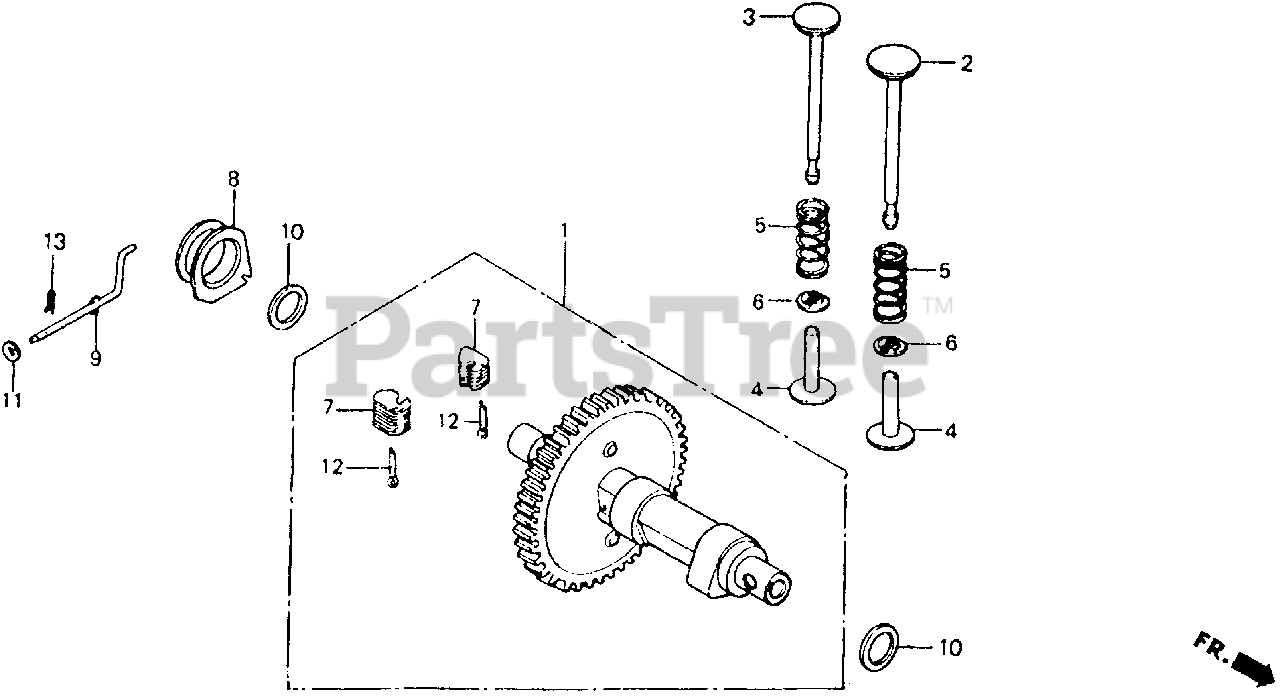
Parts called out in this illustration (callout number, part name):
1	CAMSHAFT ASSY.
2	VALVE, IN.
3	VALVE, EX.
4	LIFTER, VALVE (34.39)
4	LIFTER, VALVE (34.66)
5	SPRING, VALVE
6	RETAINER, VALVE SPRING
7	WEIGHT, GOVERNOR
8	SLIDER, GOVERNOR
9	SHAFT, GOVERNOR ARM
10	WASHER, THRUST (18MM)
11	WASHER, PLAIN (5MM)
12	PIN, COTTER (3.0X45)
13	PIN, LOCK (8MM)
